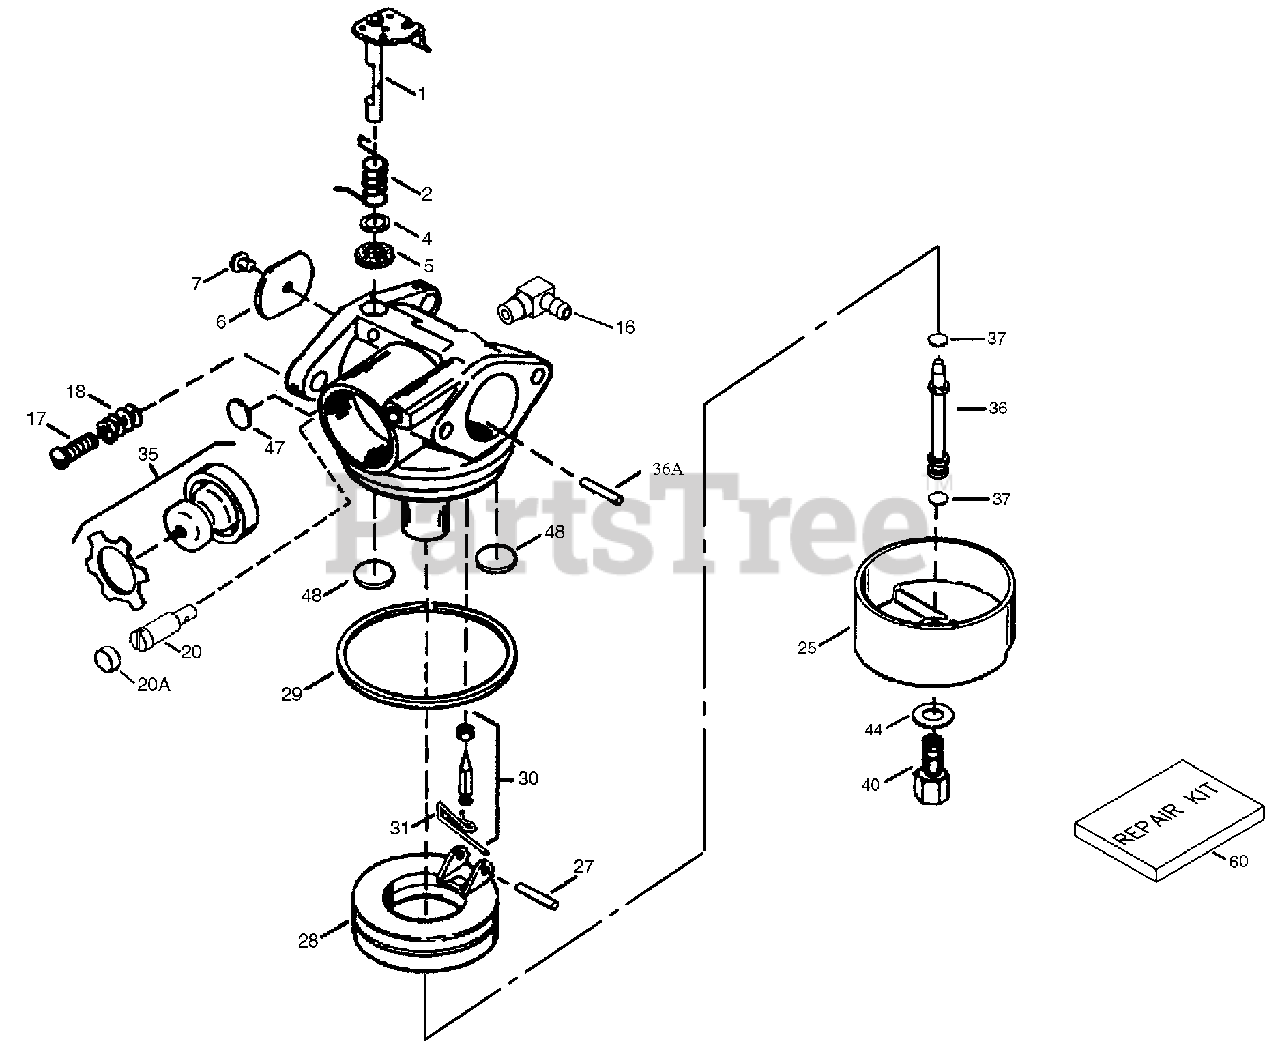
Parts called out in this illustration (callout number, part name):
1	Shaft & Lever
2	Spring-Return
4	Washer
5	Dust Seal
6	Shutter-Throttle
7	Screw
16	Fitting-Fuel
17	Screw-Idle
18	Spring
20	Idle Restrictor Screw
20A	Idle Restrictor Screw
25	Bowl, Flat
27	Float Shaft
28	Float (Plastic)
29	Gasket
30	Inlet Needle, Seat,& Clip (Incl. 31)
31	Clip
35	Primer Bulb/RetainerRing
36	Nozzle-Main
36A	Bowl Vent Tube
37	O-Ring
40	High Speed Bowl Nut
44	Washer-Bowl
47	Plug-Welch
48	Plug
60	Repair Kit
61	Gasket-Carburetor
